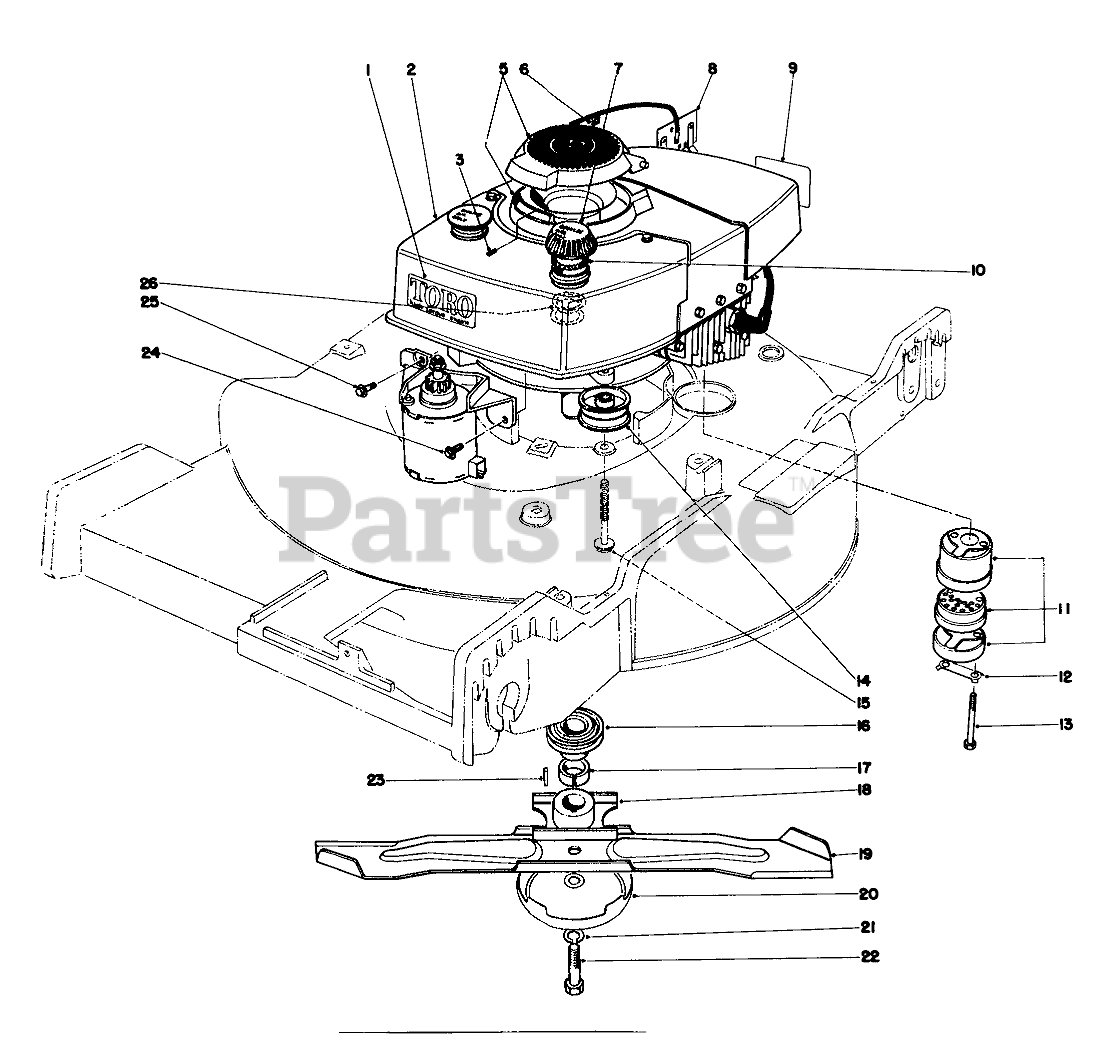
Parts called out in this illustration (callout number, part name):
1	High Torque
2	Engine (TNT 120-12004)
3	SPRING PIN
5	Cover
6	WIRE CLIP
7	Gas Cap Assembly (Incl. Ref. #10 & 26)
8	SWITCH & TERM BLK CVR
9	Decal Maintenance
10	GASKET
11	Muffler Assembly (Incl. Ref. #12 & 13)
12	CLIP - LOCKING
13	SCREW-HH
14	IDLER PULLEY
15	3/8-16 X 2-3/4 CAPSCR
16	PULLEY DRIVER
17	Pulley Spacer
18	BLADE RETAINER WA
19	Blade
20	AntiScalp Cup
21	WASHER-LOCK
22	BLADE SCREW
23	KEY-SQUARE
24	SCREW
25	Screw
26	GAS CAP BAFFLE
